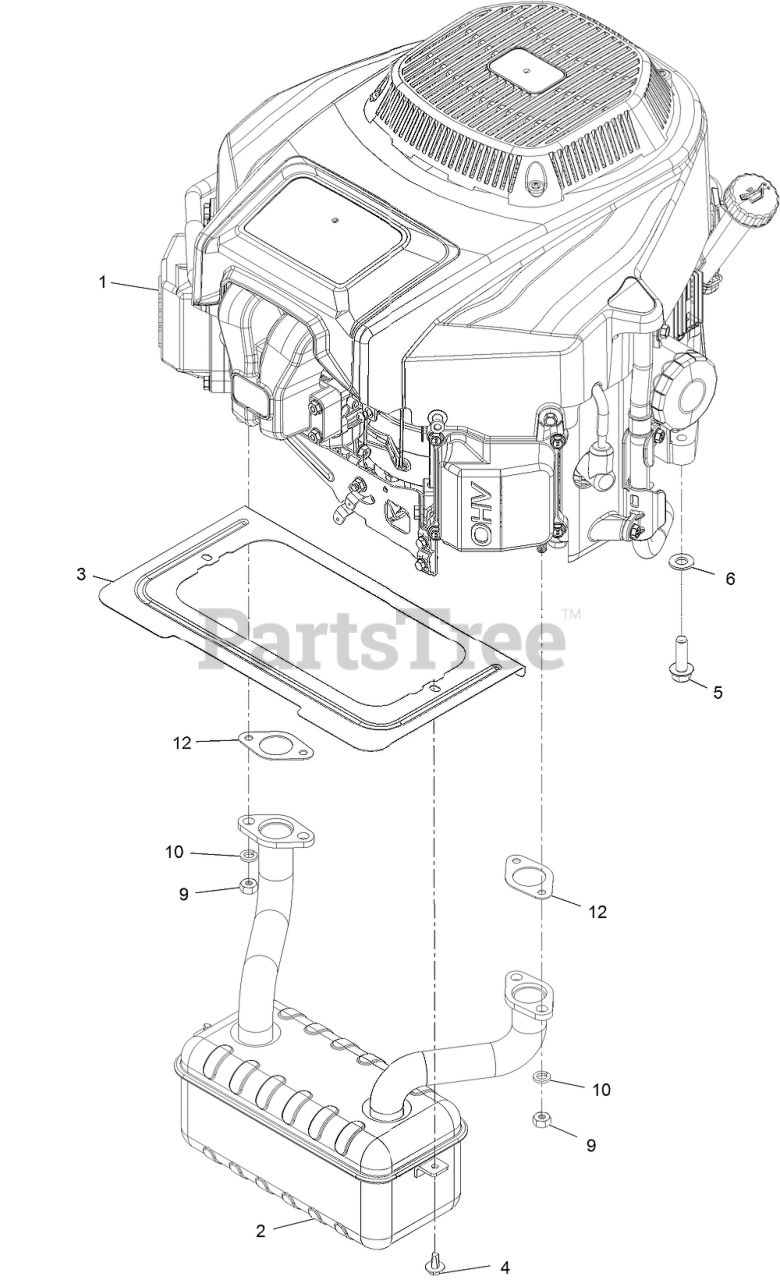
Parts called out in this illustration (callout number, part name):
1	Engine-2P77F
2	MUFFLER
3	SHIELD-HEAT
4	SCREW-HHFTF
5	SCREW-THD
6	WASHER-FLAT
10	WASHER-LOCK, SPLIT
12	GASKET-EXHAUST
